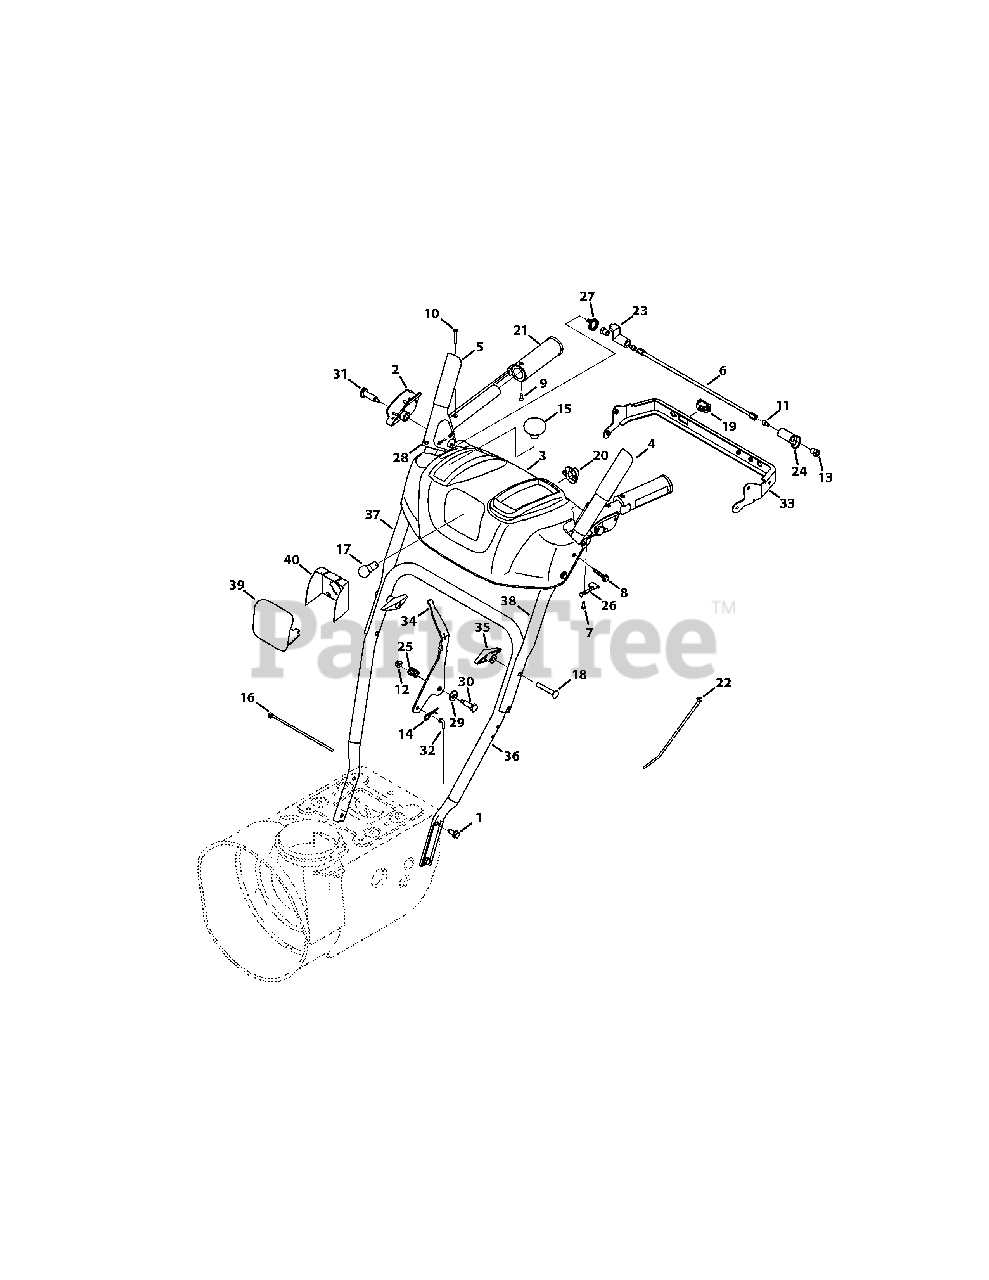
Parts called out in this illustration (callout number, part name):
1	Screw, Taptite, 5/16-18 x .750
2	Clutch Lock, RH
2	Clutch Lock, LH
3	Handle Panel, includes 39 & 40
4	Auger Engage, Black
5	Drive Engage, Black
6	Pivot Rod
7	Screw, Plastite, 8-16 x .50
8	Screw, Taptite, 1/4-20 x 1.625
9	Screw, 10-16 x 0.625
10	Screw, 10-24 x 1.375
11	Screw, 1/4-20 x .50
12	Nut, Flange Lock, 1/4-20
13	Nut, Hex, 1/4-20
14	Click Pin, .092 x 1.64
15	Shift Knob
16	Cable Tie, 7"
17	Lamp, 12.8V, 357cc Engine
18	Screw, Carriage, 5/16-18 x 2.25
19	Heated Grip Switch
20	Lamp Socket
21	Heated Grip
22	Cable Tie, Push Mount
23	Plate, Lock
24	Cam, Clutch Lock
25	Compression Spring, .39 x .60 x .88
26	Clutch Lock Spring
27	Torsion Spring, 0.8156 x .3038
28	Rubber Bumper
29	Washer, Flat, .385 x .87
30	Screw, Shield, .374 x 1.05
31	Screw, Shoulder, .437 x 1.345 x 1/4-20
32	Speed Selector Cable
33	Panel Bracket
35	Wing Knob
36	Lower Handle
37	Upper RH Handle
38	Upper LH Handle
39	Lens Panel
40	Lens Label
